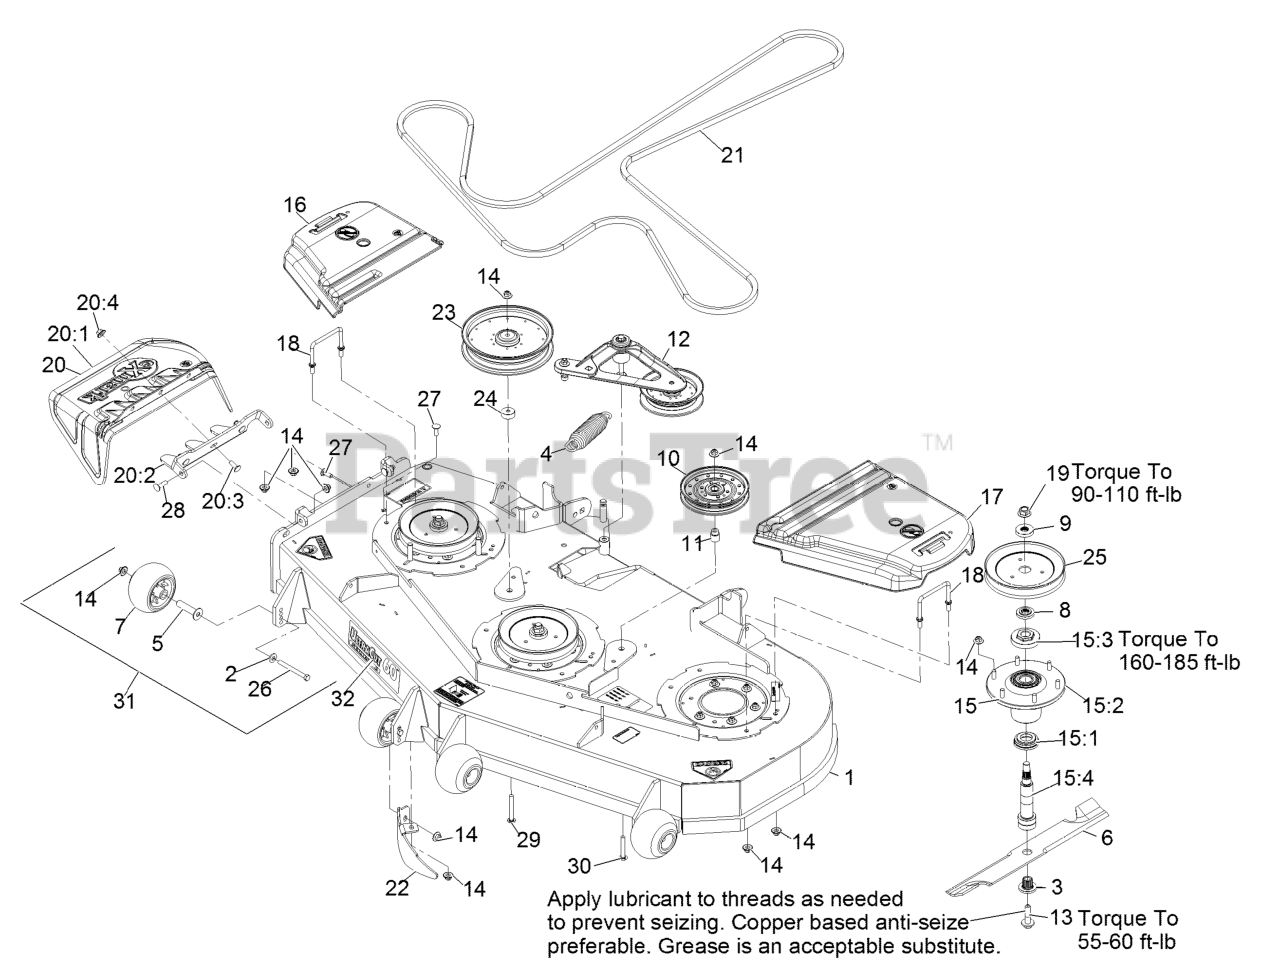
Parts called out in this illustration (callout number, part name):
1	DECK ASM,W/DECALS 60
2	WASHER-BELLEVILLE
3	BUSHING,SPLINED
4	SPRING-EXTENSION
5	AXLE, ROLLER
6	Blade-Extreme 2, 20.50"
7	ROLLER-SCALP, ANTI
8	SPACER,SPLINED STEPPED
9	SPACER,SPLINED
11	BUSHING-IDLER
12	DECK IDLER ASM
13	SCREW,SEMS 1/2-20 X 2.19
14	Nut-Nyloc 3/8-16 Flg
15	ASM,SPINDLE HOUSING
15:1	GUARD,BOTTOM
15:2	ASM,CUTTER HOUSING
15:3	NUT, SPINDLE 7/8-14
15:4	SPINDLE,DOUBLE SPLINE
16	COVER-BELT, RH
17	COVER-BELT, LH
18	WIREFORM-COVER
19	NUT-FLANGE, CENTERLOCK
20	ASM,DISCHARGE CHUTE
20:1	CHUTE,DISCHARGE
20:2	BRACKET,DISCHARGE CHUTE
20:3	SCREW-CARR
20:4	Nut-Nyloc 3/8-16 Flg
21	BELT,V-5V-198.75
22	DOGLEG - LZ60
23	PULLEY-IDLER
24	SPACER-IDLER
25	SHEAVE,BLADE DRIVE 7.25
26	SCREW-HH 3/8-16 X 3 3/4 GR 8
27	SCREW-CARR
28	Bolt-Carriage 3/8-16 X 1 1/4
29	SCREW-CARR
30	SCREW-CARR
31	KIT, ANTI-SCALP ROLLER
32	DECAL,ULTRACUT 60 SERIES
